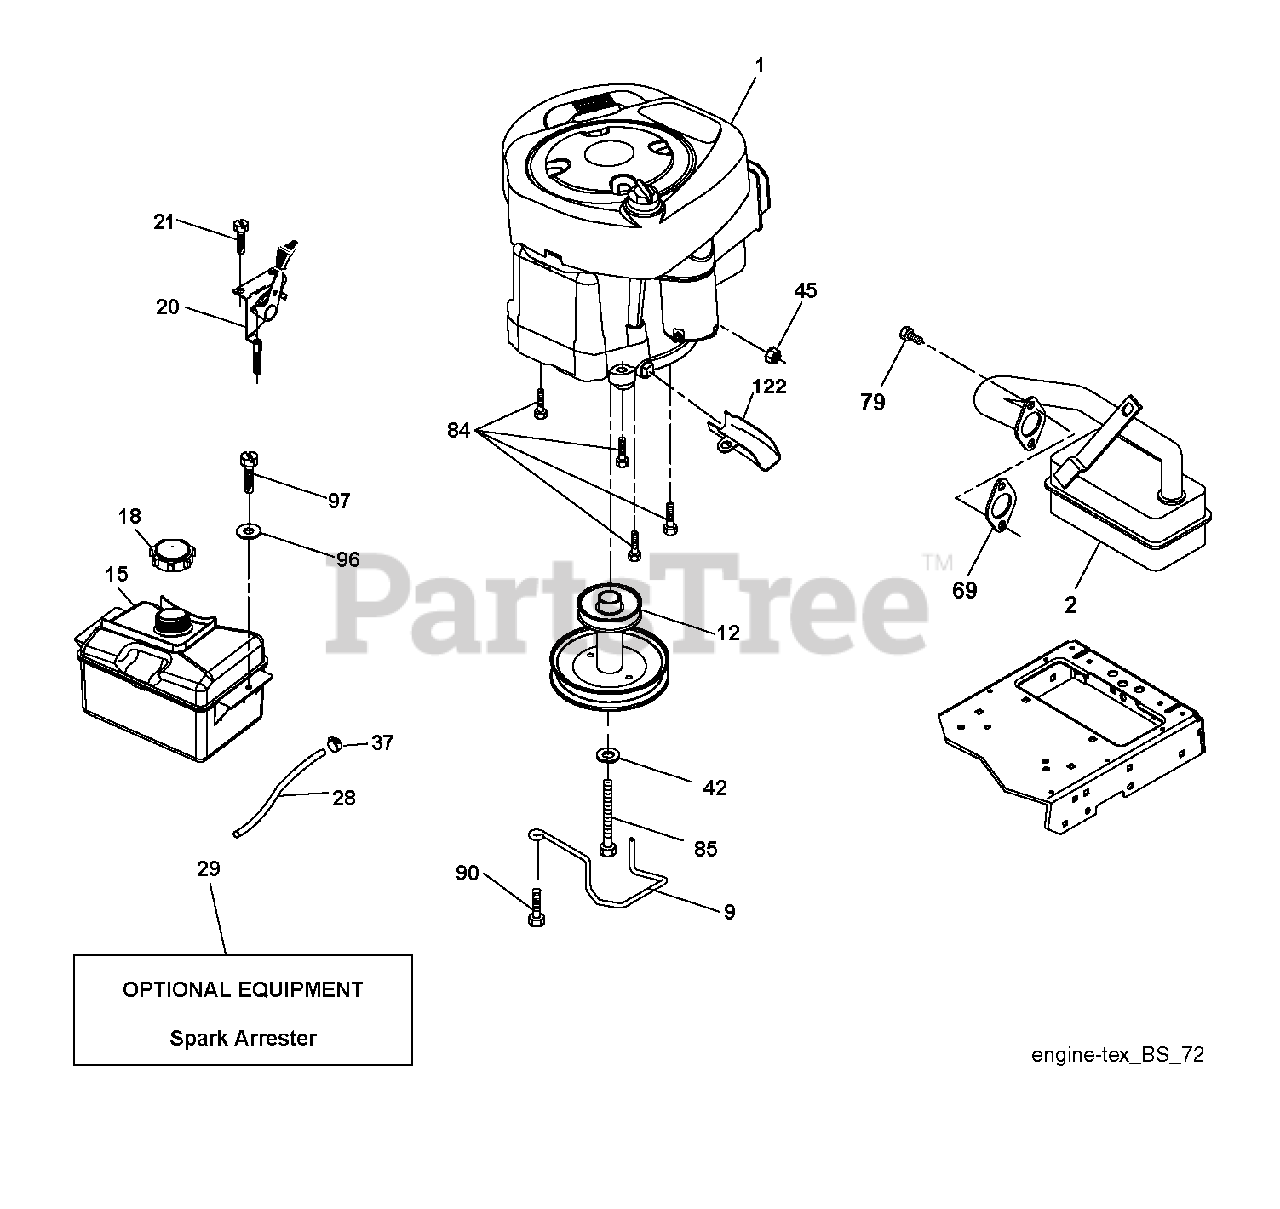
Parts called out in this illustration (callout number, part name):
2	MUFFLER.LT.BRIGGS.14HP.IC/OHV
9	KEEPER.BELT.ENGINE.3.25
12	PULLEY ENGINE
15	FUEL.TANK.ASM.1.5.GAL.NON-EPA
18	CAP.FUEL.2 WAY VENT
21	SCREW.#10 X 0.750.BOS (2 2)
28	LINE.FUEL.20
29	KIT.SPARK ARRESTOR(392390 B&S)
37	HOSE CLAMP
42	LOCKWASHER
45	NUT
79	SCREW.SOCKET HD.5/16-1
84	SCREW.3/8-16
85	BOLT HEX 7/16-20X4-1/4"
90	SCREW 3/8-16X1
97	SCREW HEXWSHR 1/4-20X3/4
122	EXTENSION DRAIN OIL
